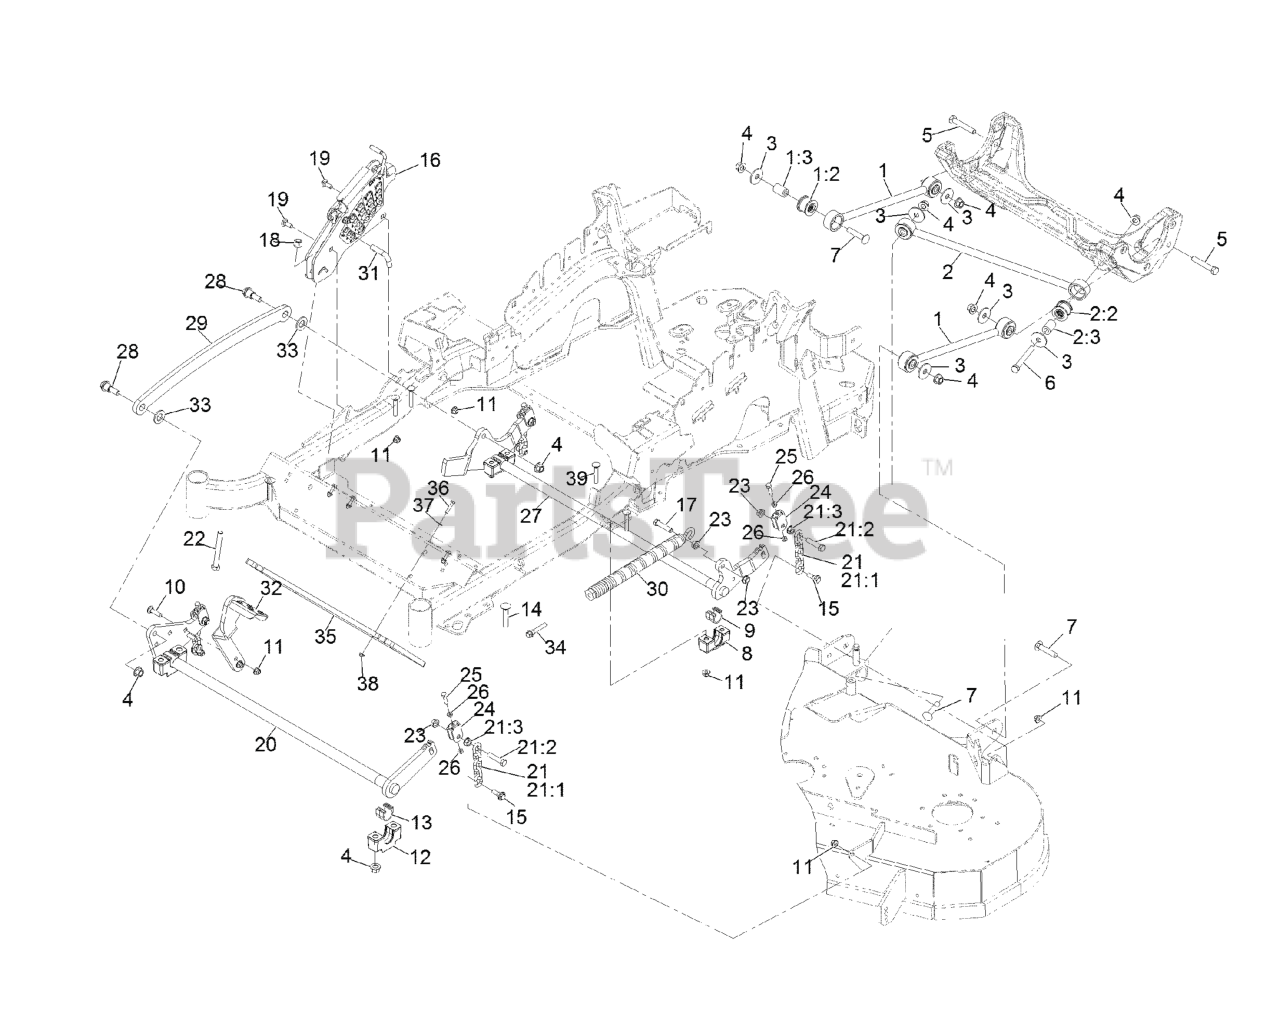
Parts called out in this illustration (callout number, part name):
1	DECK STRUT ASM
1:2	BUSHING-SUSPENSION, RUBBER
2	PANHARD ROD ASM
2:2	BUSHING-SUSPENSION, RUBBER
3	WASHER-THRUST
4	Nut-Lock 1/2-13
5	SCREW-HH
6	SCREW-HH
7	SCREW-CARR
8	SUPPORT-CROSS SHAFT, BEARING REAR
9	BEARING-CROSS SHAFT, REAR
10	SCREW-CARR
11	NUT-HF, NI
12	SUPPORT-CROSS SHAFT, BEARING
13	BEARING-CROSS SHAFT, FRON
14	Bolt-Carriage 1/2-13 X 2 1/2 Spl Neck
15	SCREW-SHOULDER, HHF
16	HOC ASM
17	SCREW-HH
18	NUT-LOCK, NI
19	BOLT-CARR
20	DECKLIFT-FRONT
21	DECK LIFT CHAIN ASM
21:1	CHAIN-LIFT, DECK
21:2	SCREW-HH
22	BOLT-TAP
24	YOKE-ADJUST, DECK
25	SCREW-HH
26	NUT-JAM
27	LIFT-DECK, REAR
28	SCREW-SHOULDER, HHF 1/2-13 X 1.12
29	LINK-LIFT, DECK
30	SPRING-EXTENSION
31	PIN-HOC
32	LEVER-FOOT
33	WASHER-FLAT
34	BOLT-SHOULDER
35	WEIGHT-TOE BOARD
36	SCREW-HH
37	WASHER-FLAT
39	Bolt-Carriage 3/8-16 X 2 1/4
